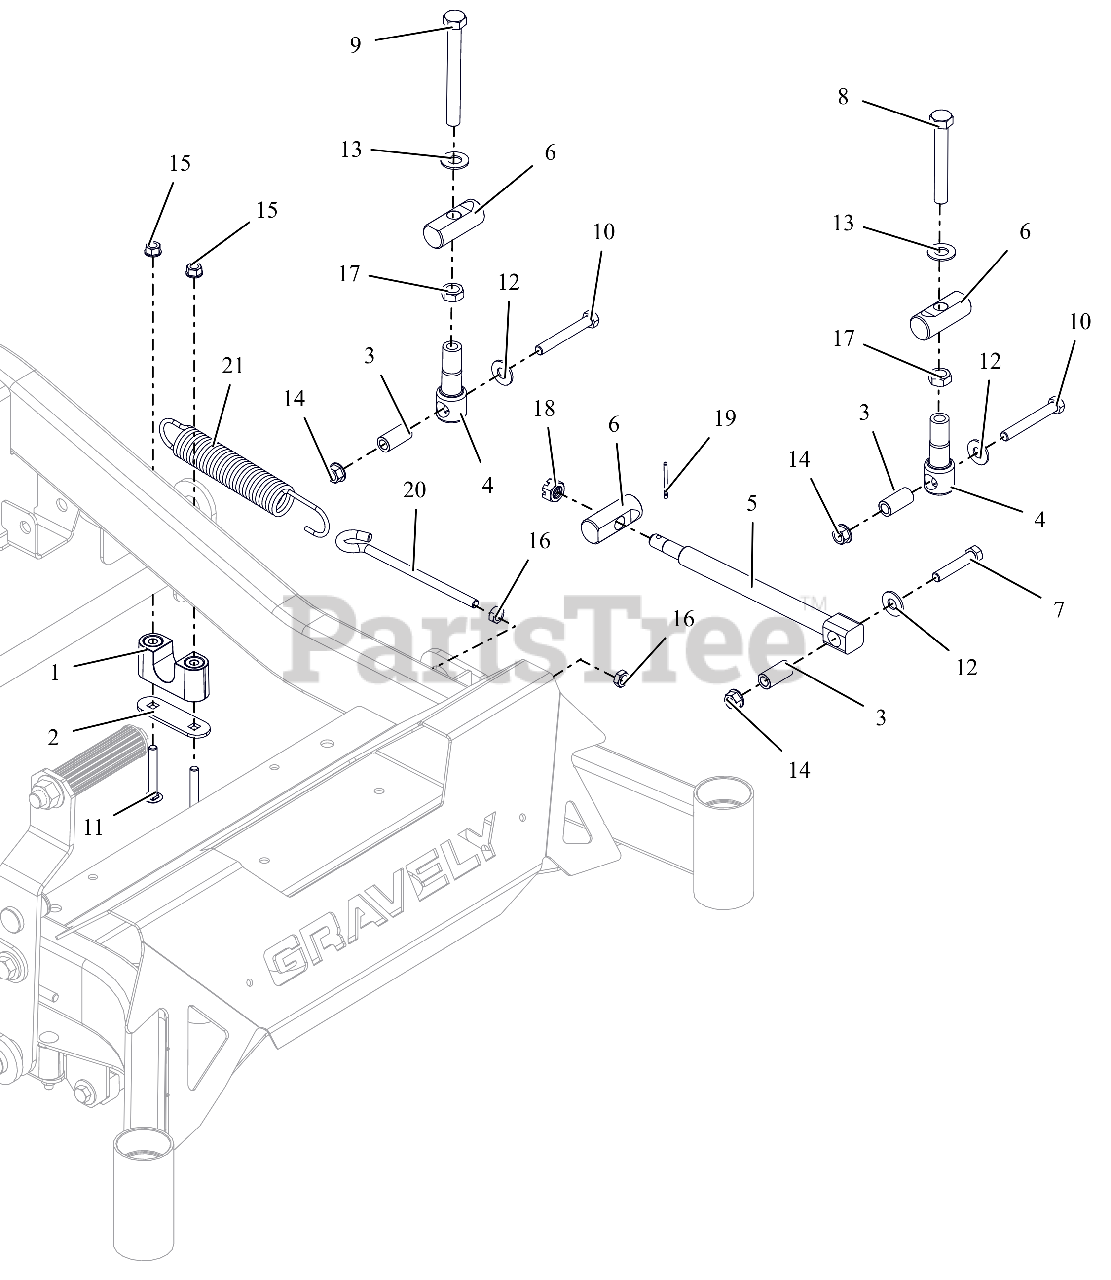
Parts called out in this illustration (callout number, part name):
1	ASM-BUSHING, DECK LIFT
2	PLATE, BEARING SUPPORT
3	SPACER, DECK LEVELING
4	LINK, DECK LIFT FORMED
5	DRAG,LINK-HD
6	PIN, DECK LIFT
7	BLT,HEX .38-16X2.00 G5 ZCC
8	BLT, HEX 0.5-13X3.5F GR5 ZCC
9	BLT, HEX .50-13X4.50F G8 ZCC
10	BLT, HEX .38-16X2.75 G8 ZCC
11	BLT, RHSSN.31-18X2.25 G5 ZCC
12	WSHR,FLT .438X1.00X.083 ZCC
13	WSHR, FLT .557X1.040X.102 ZCC
14	NUT-LK-TOP-FLG .38-16 ZC120
15	NUT,LK-CTR-FLG .31-18 GF ZCC
16	NUT-JAM .375-16 G2 ZCC
17	NUT-JAM .500-13 G2 ZCC
18	NUT-SL .50-13
19	PIN,CTR.12X1.25EXTPRSQCT ZC120
20	BOLT,.38-16 X 5.25-.62 DIA EYE
21	SG-TENS .162X1.25X8.25 WLD 25
